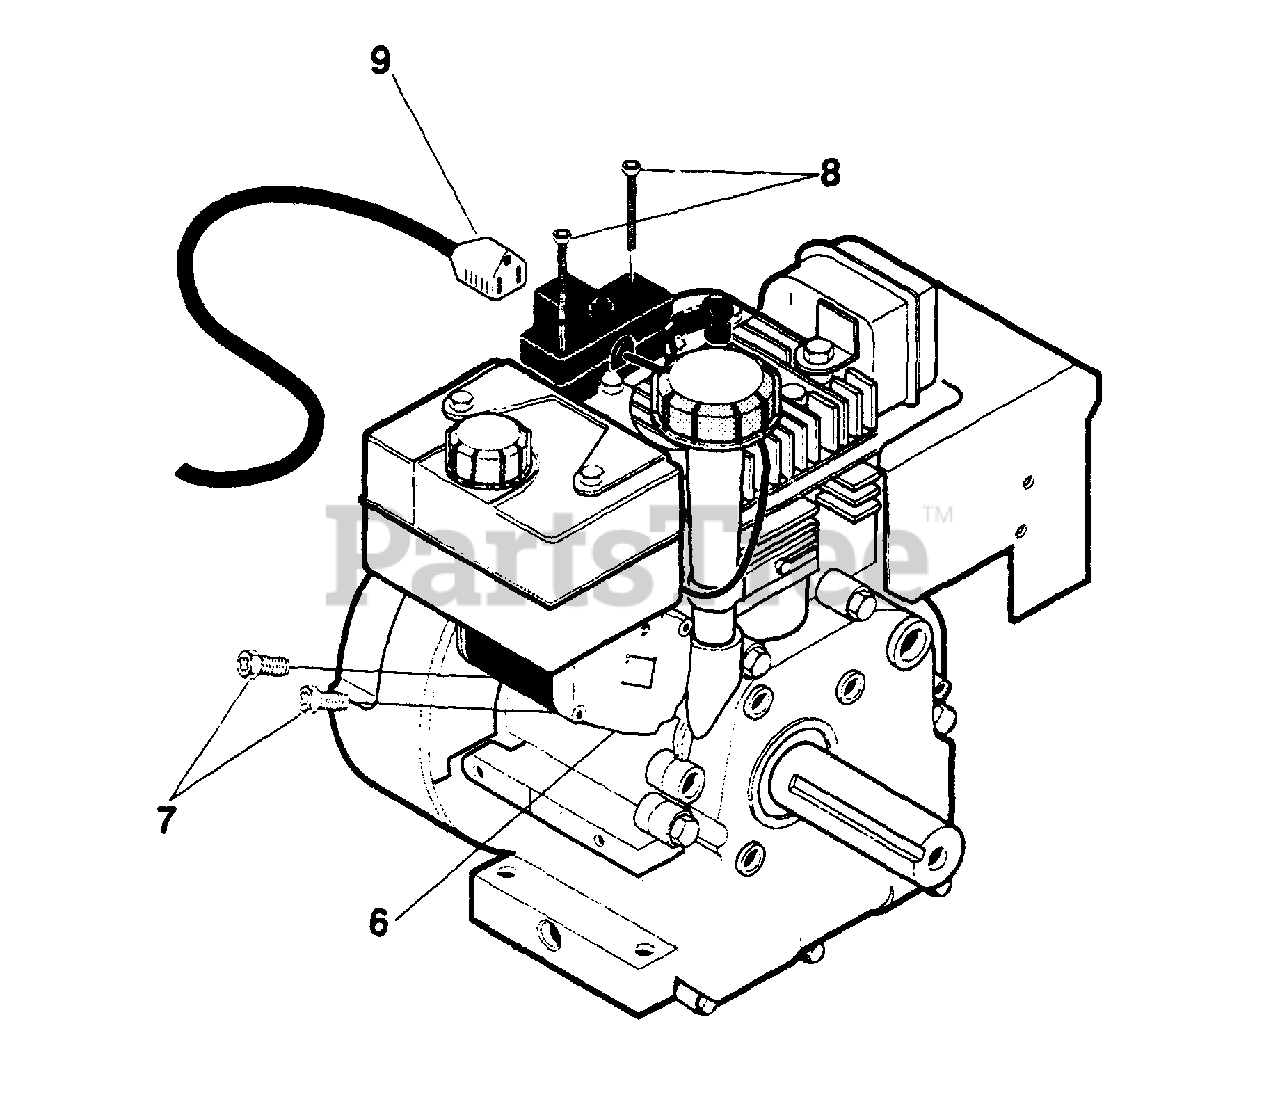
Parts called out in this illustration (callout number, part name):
6	MOTOR, STARTER TEC 120V
7	SCREW 1/4-20X.50 WASEMSTOR
8	SCREW #6-32X2.50
9	CORD, STARTER MOTOR
